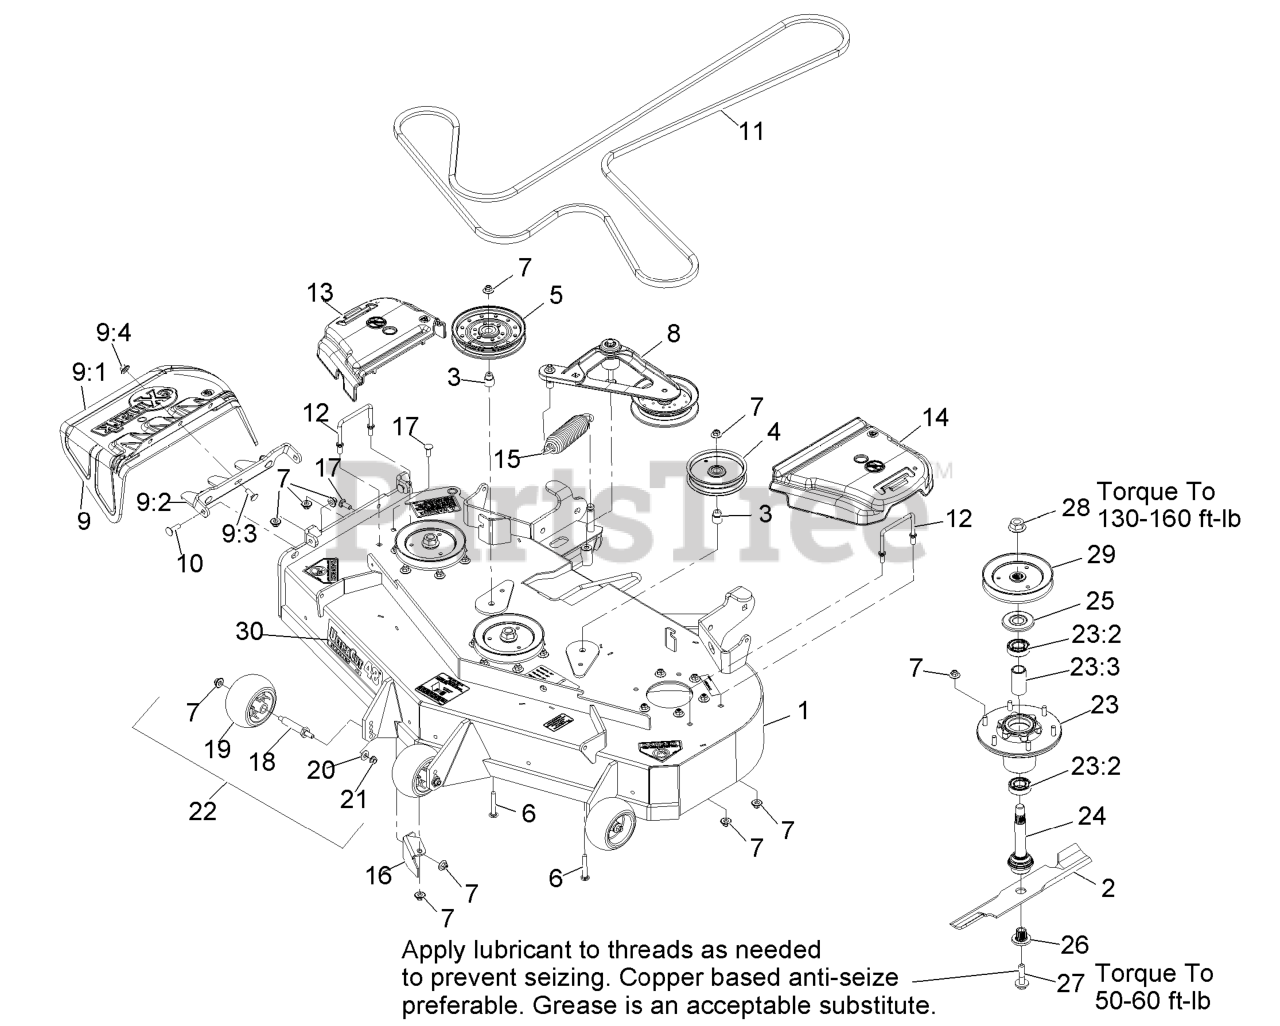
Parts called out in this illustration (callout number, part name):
1	ASM,DECK W/DECALS 48
3	BUSHING-IDLER
4	PULLEY-IDLER
6	SCREW-CARR
7	Nut-Nyloc 3/8-16 Flg
8	DECK IDLER ASM
9	ASM,DISCHARGE CHUTE
9:1	CHUTE,DISCHARGE
9:2	BRACKET,DISCHARGE CHUTE
9:3	SCREW-CARR
9:4	Nut-Nyloc 3/8-16 Flg
10	Bolt-Carriage 3/8-16 X 1 1/4
11	BELT
12	WIREFORM-COVER
13	COVER-BELT, RH
14	COVER-BELT, LH
16	BAFFLE,DISCHARGE
17	SCREW-CARR
19	ROLLER-SCALP, ANTI
20	WASHER-BELLEVILLE
21	NUT-HHF, WHIZ
23	ASM-CUTTER HSG WITH BEARINGS
23:2	BEARING-BALL
23:3	SPACER-BEARING
24	ASM-SPINDLE AND SEAL
25	GUARD,BEARING TOP .989
26	BUSHING,SPLINED
27	SCREW,SEMS 1/2-20 X 2.19
28	NUT-FLANGE
29	SHEAVE,BLADE DRIVE 5.90
30	DECAL,ULTRACUT 48 SERIES
